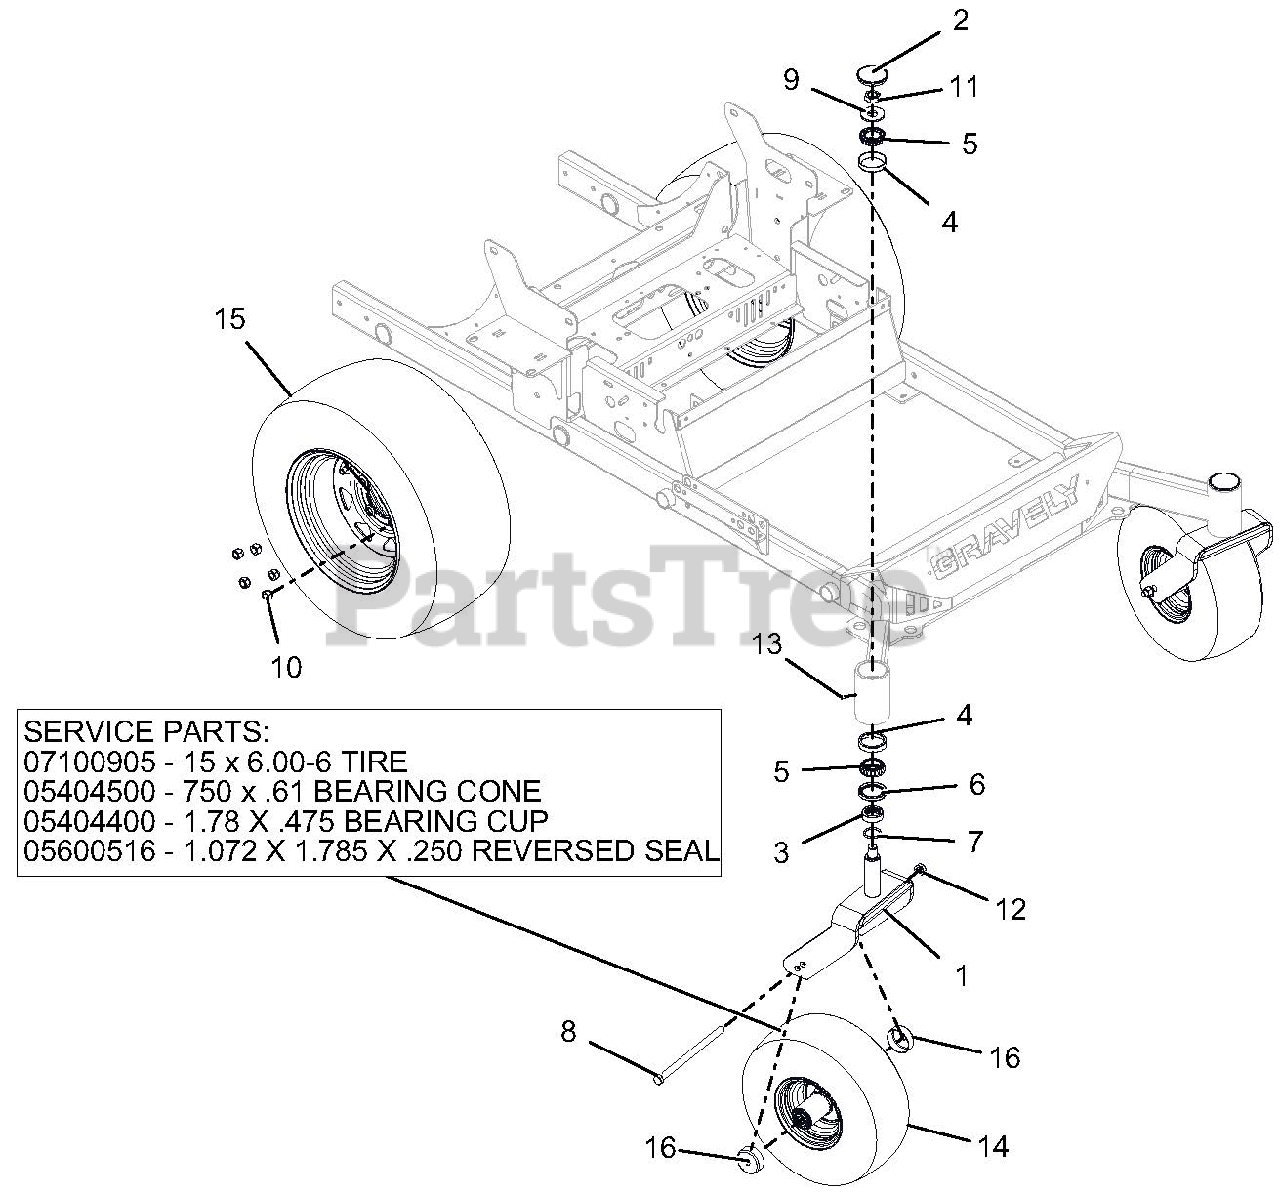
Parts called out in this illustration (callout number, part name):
1	WMT, CASTER FORK - RED
2	CAP, DUST
3	SPCR, FRONT CASTER FORK
4	BRG, CUP 2.328 X .465
5	BRG, CONE 1.250 X .660
6	SEAL, OIL 1.75 X 2.332 X .312
7	O-RING, .139 W X 1.234 ID
8	BLT-HEX .50-13X9.00 GR5 YWZC
9	WSHR-FL-STL.812X2.00X.148YWZC
10	NUT, LUG .500-13
11	NUT-LK-TOP-JAM .75-16 YWZC
12	NUT, LK-TOP-FLG .50-13 YWZC
13	FITTING, .250-28 FLUSH MOUNT GREASE
14	TIRE/WHEEL, 15 X 6.00-6 SMOOTH
14	16 X 6.00-6 TIRE
14	750 X .61 BEARING CONE
14	1.78 X .475 BEARING CUP
14	1.072 X 1.785 X .250 REVERSED SEAL
15	TIRE/WHEEL, ASM 23 x 10.5-12
15	TIRE, 23 X 10.50-12
16	SHIELD, WHEEL BEARING
